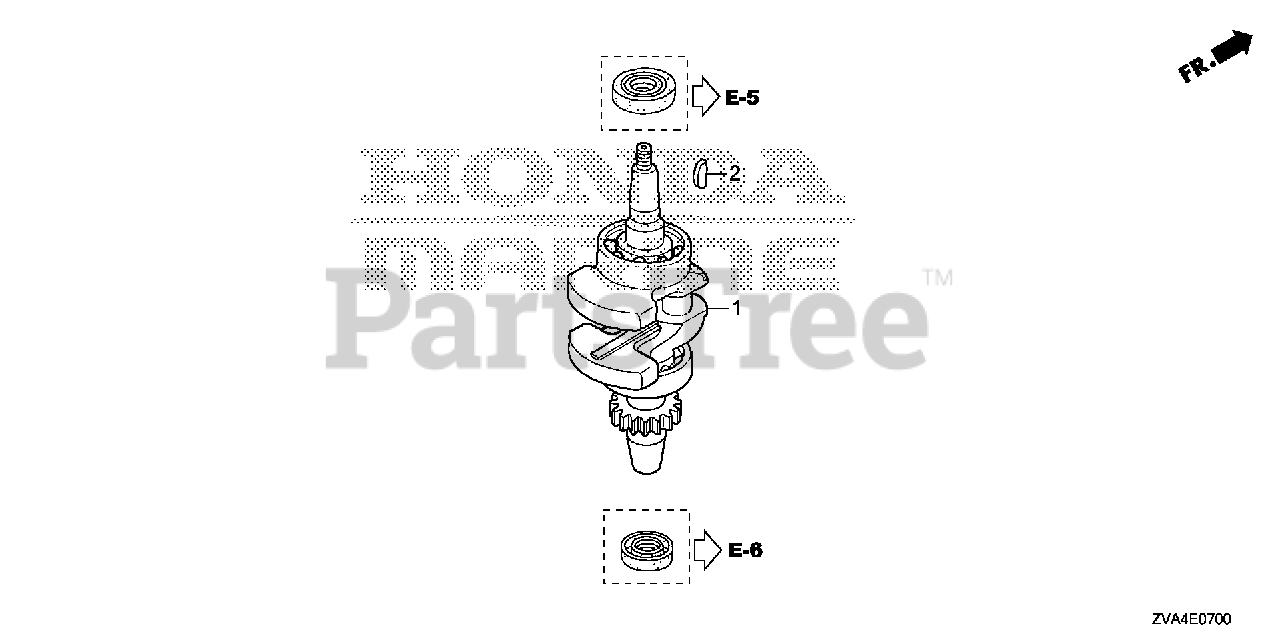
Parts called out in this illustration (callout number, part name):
1	CRANKSHAFT
1	CRANKSHAFT COMP
2	KEY, SPECIAL
